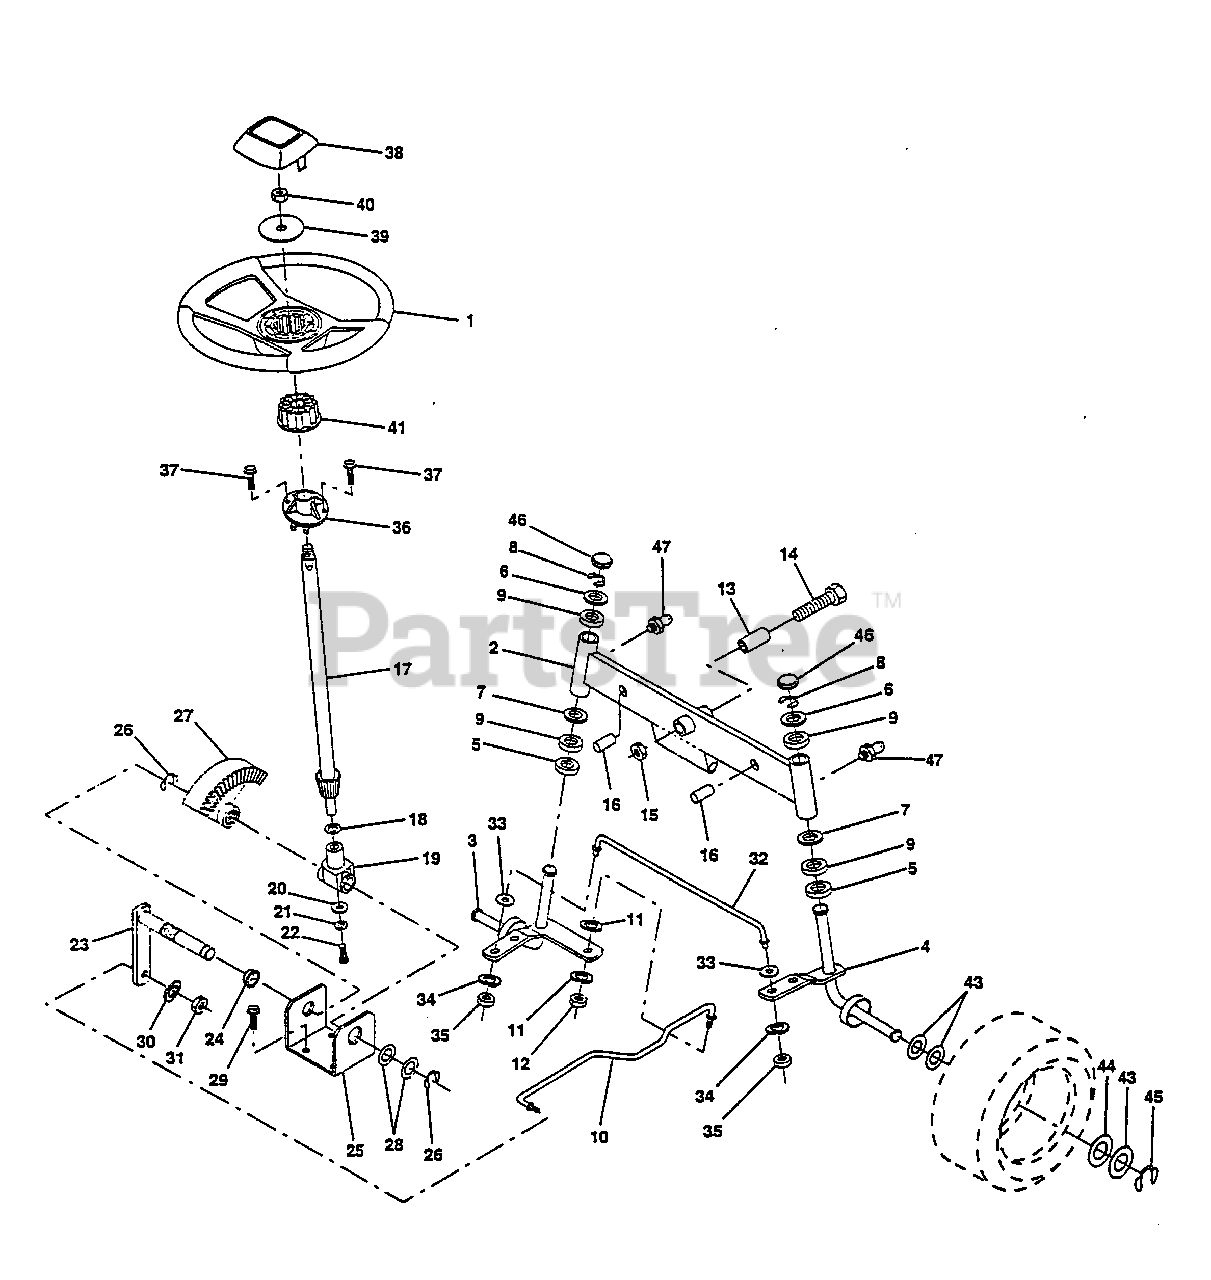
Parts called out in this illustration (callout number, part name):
1	Wheel Steering
2	Axle Asm Fr LT W/gzks 38/42
3	Spindle Asm LH
4	Spingle Asm RH
5	Bearing Race Thrust Harden
6	Washer 25/32 X 1-5/8 X 16 Ga
7	Washer 27/32 X 1-1/4 X 16 Ga
8	Ring Klip #t5304-75
9	Bearing Col Strg
10	Link Drag Sol Ball Jt
11	Washer Lock Hvy Hlcl Spr 3/8
12	Nut Fin 3/8-24 Unf
13	Spacer Bearing Axle Front
14	Bolt Hex 5/8-11 Unc X 3-1/2
15	Nut Lock Flange 5/8-11 Unc
16	Pin Axle 5/8 X 1 55/1 54 Lg
17	Shaft Asm Strg 18 31x3/4
18	Washer Thrust 515x 750x 033
19	Suport Shaft
20	Washer Shim 1/4 X 5/8 X 062
21	Washer Lock Hvy Helical 1/4
22	Screw Hex Socket 1/4-20 X 5/8
23	Shaft Asm Pittman
24	Nyliner Snap In
25	Bracket Steering
26	Ring Klip #t5304-75
27	Gear Sector
28	Bearing Race Thrust Harden
29	Screw Thdrol 3/8-16x3/4 Ty-tt
30	Washer Lock Hvy Hlcl 3/8
31	Nut Fin Hex 3/8-24 Unf
32	Rod Tie Wire Form
33	Washer 11/32 x 12116 x 16 Ga.
34	Washer, Lock, Hvy Hlcl Spr 5/16
35	Locknut 5/16-24 Unf
36	Bushing Link Drag
37	Screw Slftp #10-16 X 1/2 Ty-b
38	Insert Cap Strg Wh Aut
39	Washer 53 X 2 25 X 160
40	Nut Hex Jam Taplock 1/2-20 Unf
41	Adapter Wheel Strg
43	Washer 25/32 X 1 1/4 X 16 Ja
44	Washer 25/32 X 1-5/8 X 16 Ja
45	Ring Klip #25304-75
46	Cap Spindle Fr Top
47	Fitting Grease
